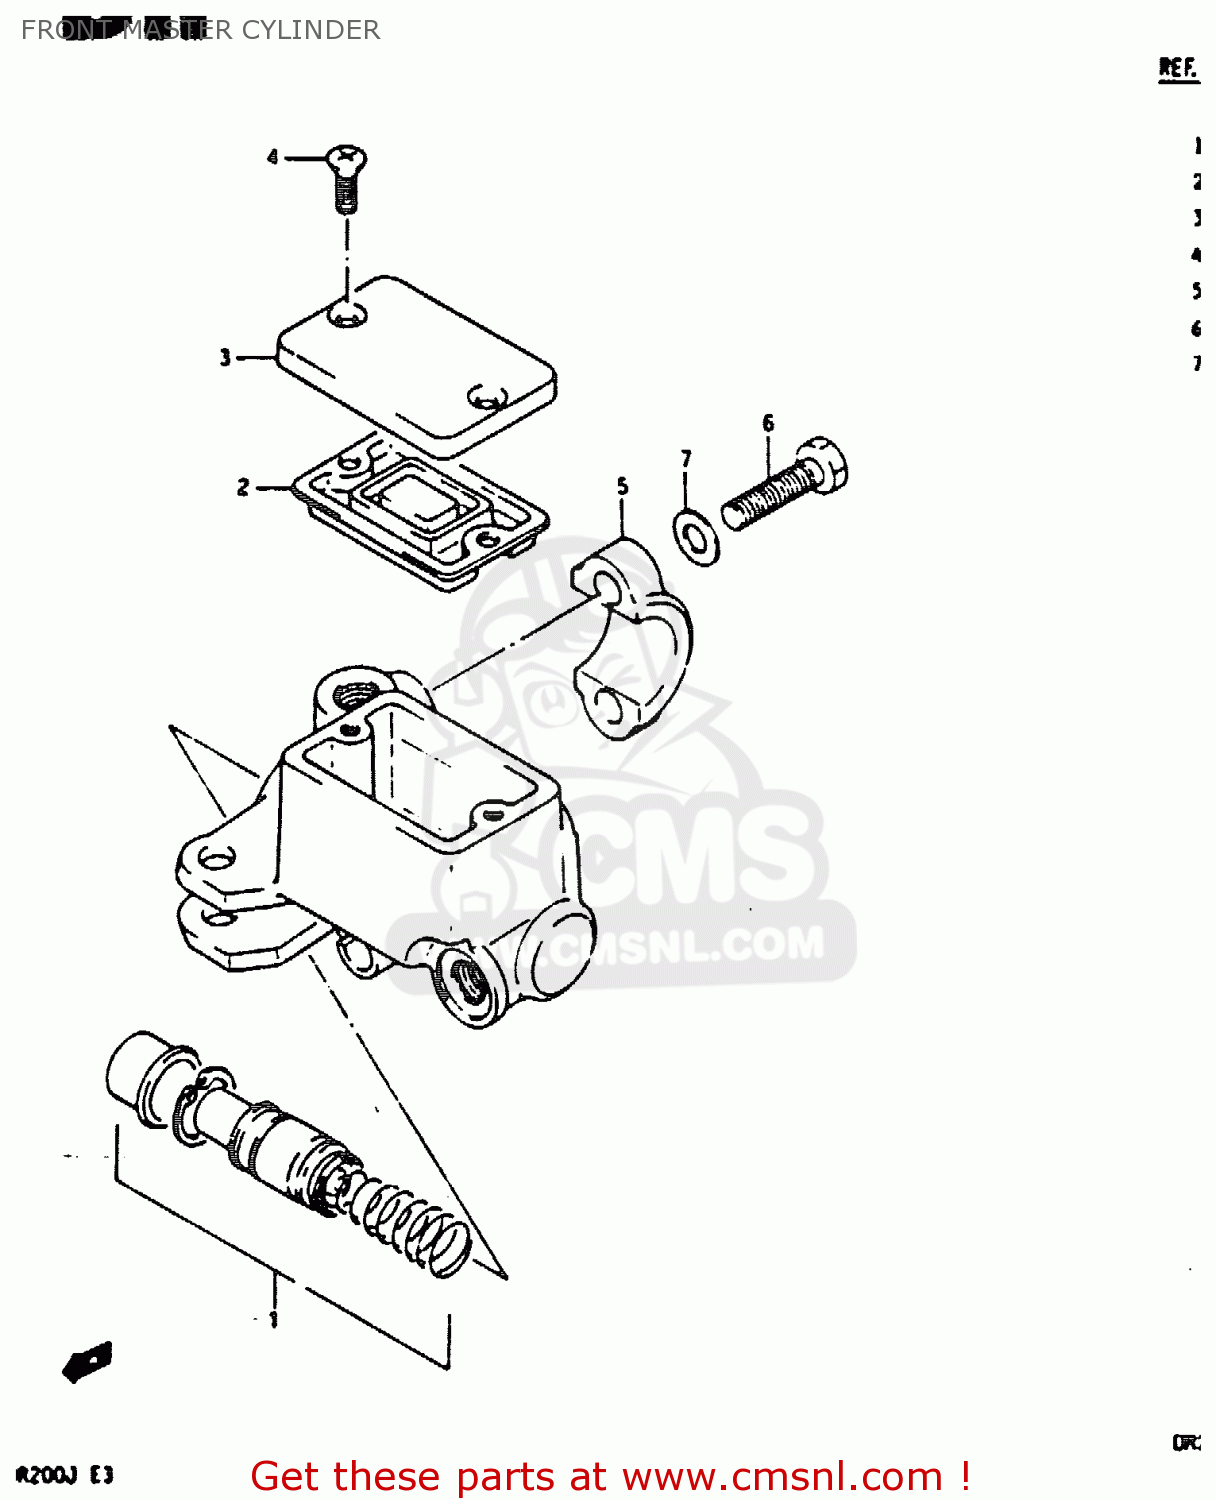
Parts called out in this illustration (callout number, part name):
1	PISTON/CUP SET
2	DIAPHRAGM
3	CAP
4	SCREW
5	HOLDER
6	BOLT
7	WASHER
